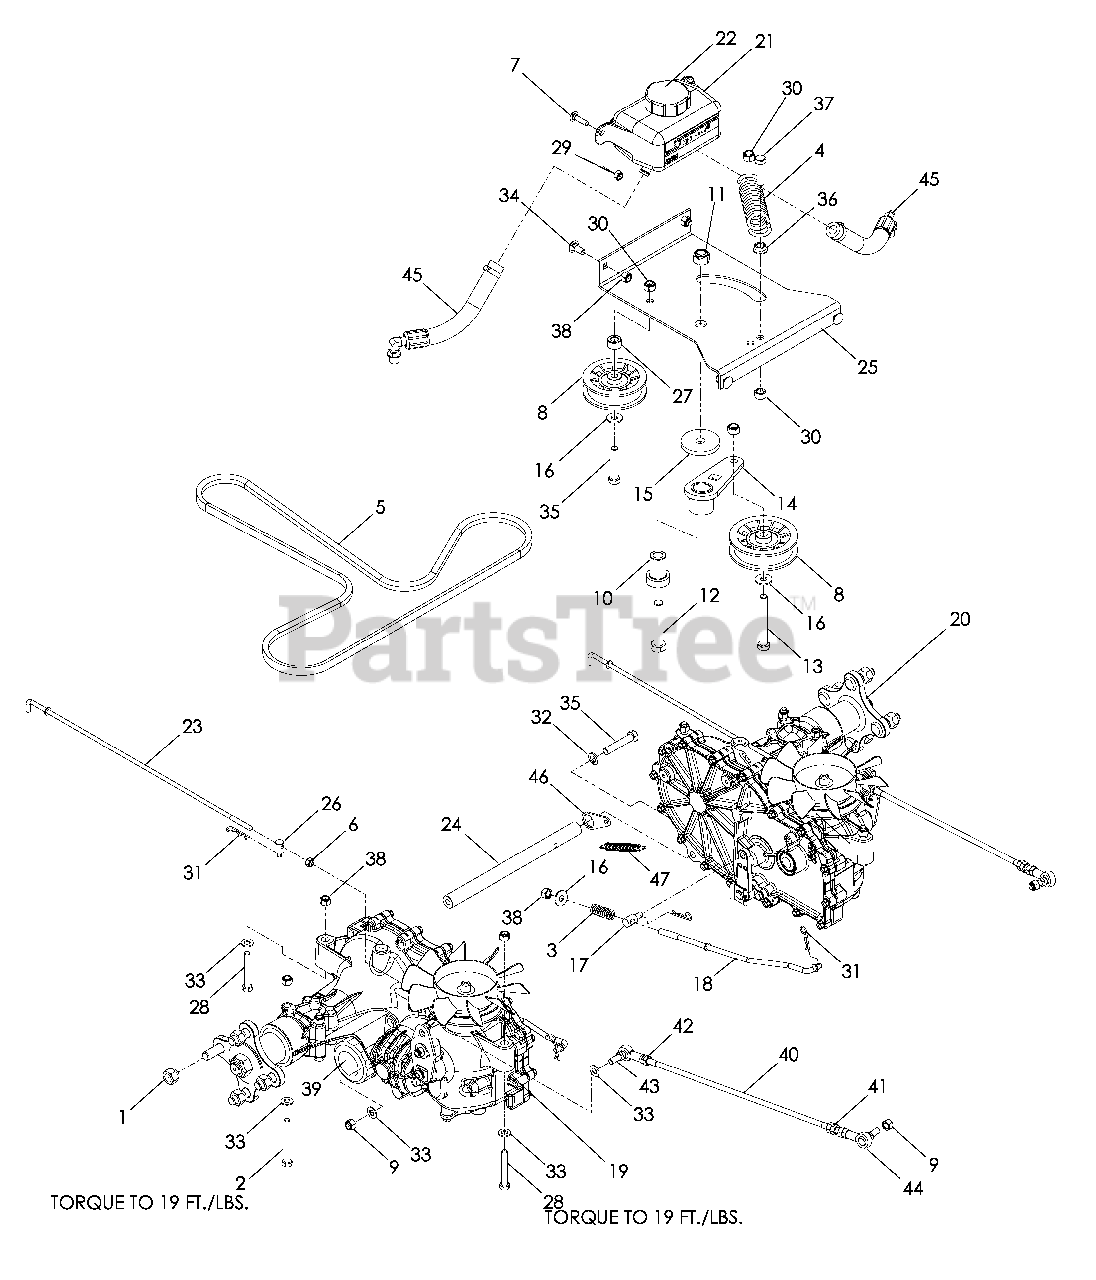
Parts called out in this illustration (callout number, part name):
1	NUT ½-20 LUG
2	HCS 5/16-18 x 2¾
4	SPRING, EXTENSION
5	BELT, PUMP
7	RHSNB ¼-20 x 1
8	PULLEY, IDLER
9	NUT 5/16 NYLOC
10	SPINDLE, IDLER
11	NUT ½-13 NYLOC
12	HCS ½-13 ¼ x 2¾
13	HCS 3/8-16 x 3 TAP
14	ARM, IDLER
15	HEAVY WASHER
16	WASHER 5/16
17	BRAKE SWIVEL
18	BRAKE LINKAGE
19	ZT2800, RIGHT
20	ZT2800, LEFT
21	EXPANSION TANK W/CAP
23	BYPASS LINKAGE
24	2800 CROSS SUPPORT
25	PULLEY, IDLER PLATE
26	SWIVEL, ¼-28
28	HCS 5/16-18 x 2¼
29	NUT ¼-20 NYLOC
30	NUT 3/8-16 NYLOC
31	PIN, HAIR, .073 x 17/16
32	WASHER 3/8
33	WASHER 5/16 SAE
34	RHSNB 5/16-18 x ¾
35	HCS 3/8-16 x 2
36	NUT 3/8-16 WHIZLK
37	HCS 3/8-16 x 1½
38	NUT 5/16-18 NYLOC
39	OIL FILTER
40	DRIVE LINKAGE
41	NUT 5/16-24
42	NUT 5/16-24, LH
43	ROD END, LEFT
44	ROD END, RIGHT
46	TAB, SPRING
